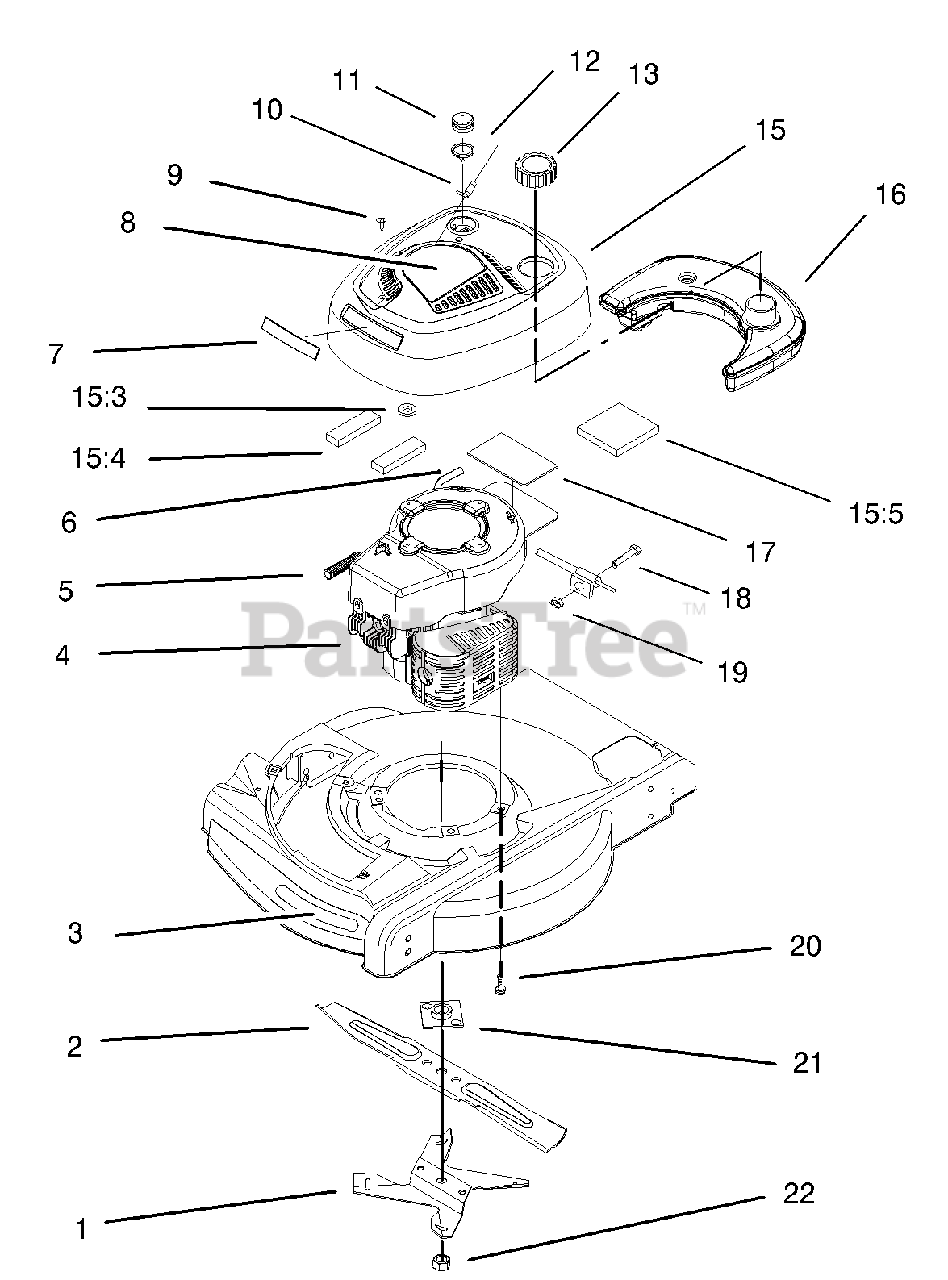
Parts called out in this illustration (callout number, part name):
1	FAN-MULCHING
3	DECAL-DECK
4	Engine ASM
5	SPRING-COMPRESSION
6	LINE-FUEL
7	APPLIQUE-SHROUD
8	DECAL-RECOIL
10	STOP-ROPE
11	BODY-PRIMER
12	BULB-PRIMER
13	FUEL AND OIL CAP ASM
15	SHROUD and RECOIL COVER ASM
15:3	NUT-PUSH
15:4	STRIP-FOAM
15:5	STRIP-FOAM
17	PAD-FOAM
19	NUT-HEX
20	SCREW-HH
21	PLATE AND COLLAR ASM
22	NUT-BLADE
